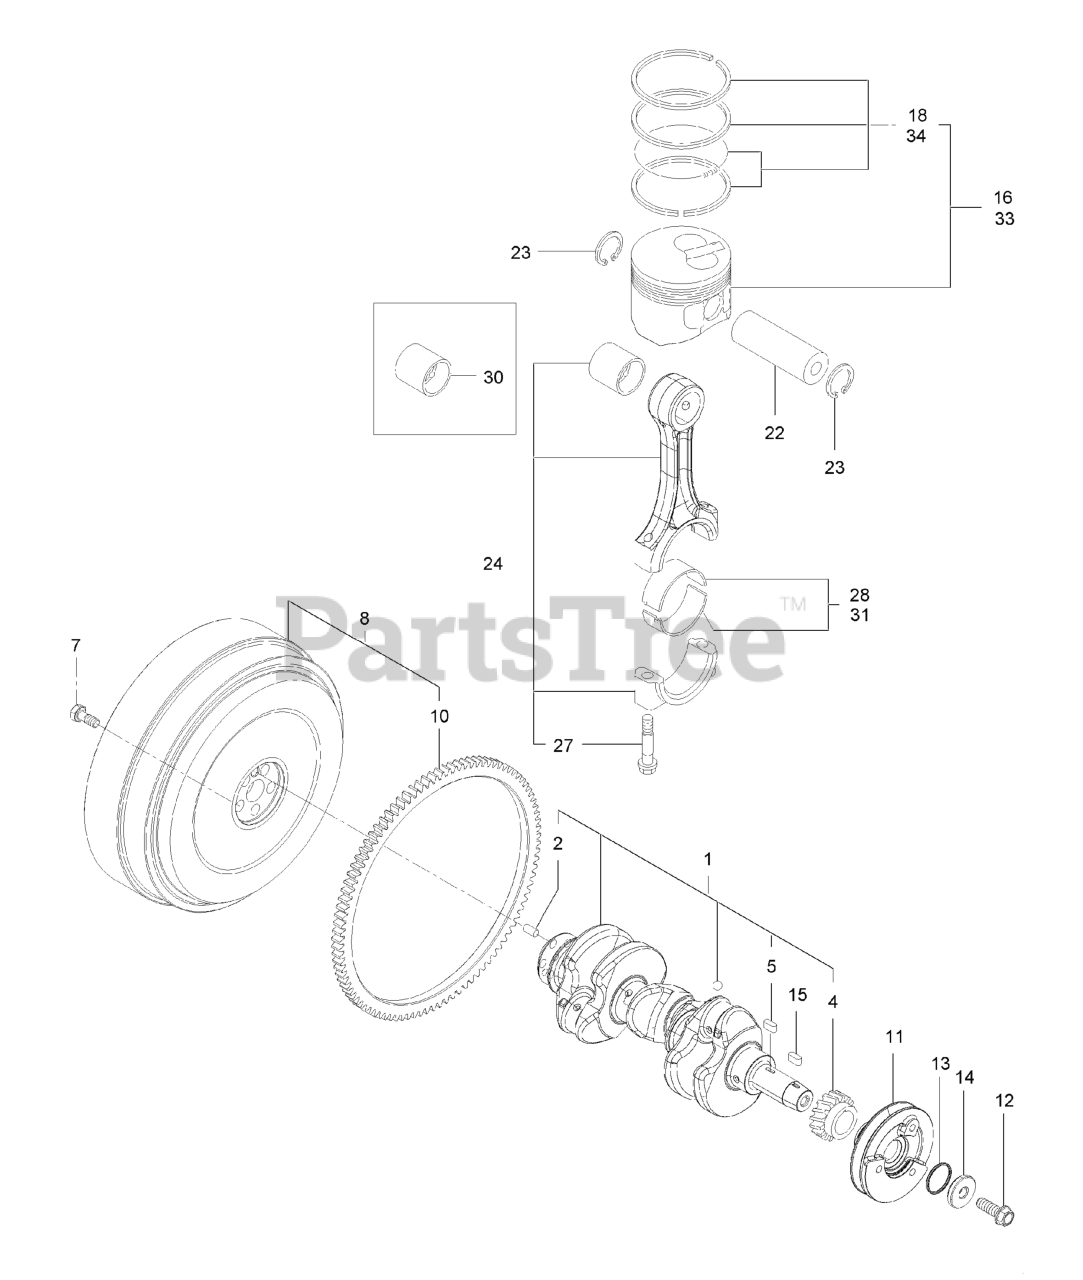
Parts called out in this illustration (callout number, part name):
1	CRANKSHAFT ASM
4	GEAR-CRANKSHAFT
7	BOLT, FLYWHEEL 5
8	FLYWHEEL ASM
10	GEAR-RING
11	V-PULLEY, CRANKSHAFT 1
12	BOLT, FLANGE 12X1.25 1
13	GASKET-WASHER
16	PISTON ASM
18	RING ASM
22	PIN-PISTON
24	ROD ASM-CONNECTING
27	BOLT-CONNECTING ROD
28	BEARING-CRANK PIN
30	BEARING-PISTON PIN
31	BEARING, PIN 0.25
33	PISTON ASM
34	RING ASM
